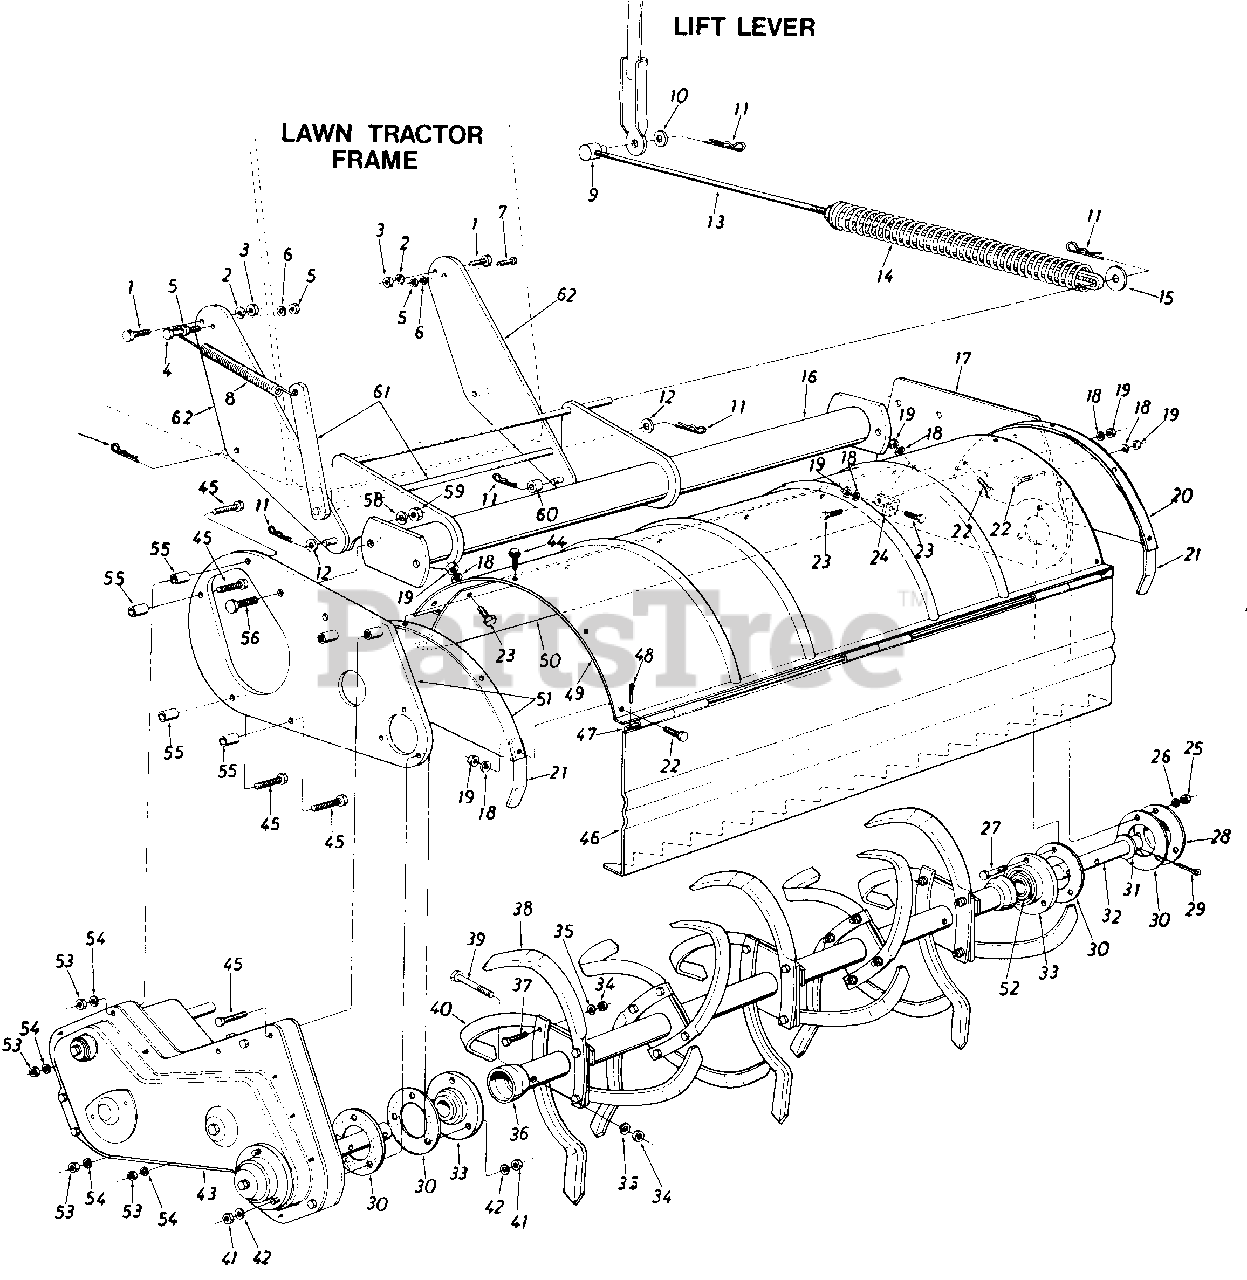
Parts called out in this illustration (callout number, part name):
1	Hex Bolt 3/8-24 x .88" Lg. *
2	L.-Wash. 3/8" I.D. Heavy Duty
3	Hex Nut 3/8-24 Thd. *
4	Hex Bolt 5/16-24 x 1.50" Lg.*
5	Hex Nut 5/16-24 Thd.*
6	L.-Wash. 5/16" I.D.*
7	Hex Bolt 5/16-24 x 1.00" Lg.*
8	Extension Spring .56" O.D. x 7.75" Lg.
9	Adjustment Ferrule 1/2-13 0 Thd.
10	Fl.-Wash. .640" I.D. x 1.24" O.D. x.060
11	Intern. Cotter Pin 1/2" Dia.
12	Fl.-Wash. .510" I.D. x 1.0" O.D. x .060
13	Lift Rod Ass'y. 39.0" Lg.
14	Compression Spring 1.50" O.D. x 15.0" Lg.
15	Fl.-Wash. .51" I.D. x 1.50" O.D. x.075
16	Pivot Bracket Assembly
19	Hex Nut 5/16-24 Thd.*
23	Hex Bolt 5/16-24 x .62" Lg. *
24	Chute Pivot Bracket
25	Hex Cent. L-Nut 5/16-18 Thd.
26	L.-Wash. 5/16" I.D.*
27	Hex Bolt 5/16-18 x 1.0" Lg. (Grade 5)
30	Gasket for Brg. Housing
31	Fl.-Wash. 1.25" I.D. x 2.00" O.D x .06
32	Tine Shaft R.D. 1.25" Dia. x 6.25" Lg.
33	Bearing Housing w/Bearing
34	Hex Nut 3/8-24 Thd.*
35	L.-Wash. 3/8" I.D. Heavy Duty
38	Tine 14" x 5/16"
39	Hex Bolt 3/8-24 x 2.25" Lg.*
40	Tine 14" x 5/16"
41	Hex Cent. L.-Nut 5/16-18 Thd.
42	L.-Wash.5/16" I.D.*
43	Chain Case Ass'y. Comp.
44	Hex Wash. TT Tap. Scr. 5/16-18 x .62" Lg.
45	Hex Bolt 1/4-20 x 2.75" Lg.*
48	Cotter Pin 1/8" Dia. x 1.00" Lg. *
53	Hex Nut 1/4-20 Thd.*
54	L.-Wash. 1/4" I.D.*
55	Spacer.28" I.D. x .62" O.D. x .90" Lg.
56	Hex Bolt 1/2-13 x 1.00" Lg.*
58	L.-Wash. 1/2" I.D.*
59	Hex Nut 1/2-13 Thd.*
60	Spacer.50" I.D. x 1.00" O.D. x.50" Lg.
61	Idler Bracket Support Arm Ass'y.
62	Pivot Bracket Support
